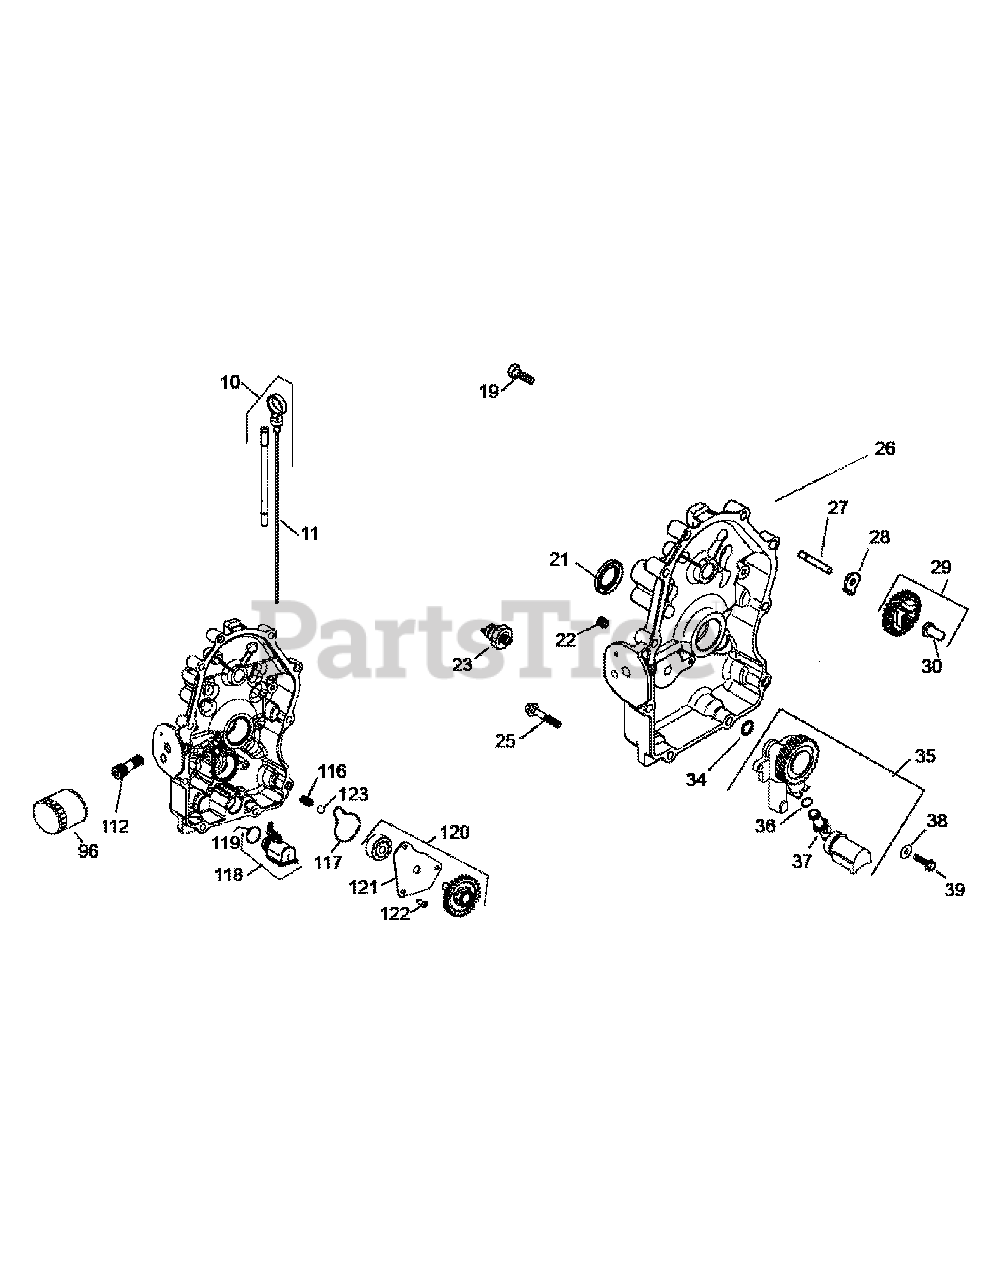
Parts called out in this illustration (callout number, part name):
10	Kit, Dipstick/Dipstick Tubes
19	Screw, Flg M8X1.25X45
22	Plug, Ctsk Pipe 1/8"
23	Switch, Oil Pressure
25	Screw, Flg M8X1.25X45
26	Plate, Closure & Bearing
27	Shaft, Governor Gear
29	Kit, Governor Gear W/Pin
30	Pin, Governor Regulating
35	Kit, Oil Pump Assy
36	O-Ring, Oil Pick-Up
37	Pick-Up, Oil
38	Washer, Flat 1/4" (O.D. 5/8")
39	Screw, Thread Forming
112	Nipple, Oil Filter
116	SPRING, COMPRESSION
117	SEAL, OIL PUMP COVER
118	PICK-UP ASSEMBLY, OIL
119	O-RING, OIL PICK-UP
120	PUMP ASSEMBLY, OIL
121	COVER, OIL PUMP
122	SCREW, BUTTON HEAD
123	PRESSURE RELIEF BALL
